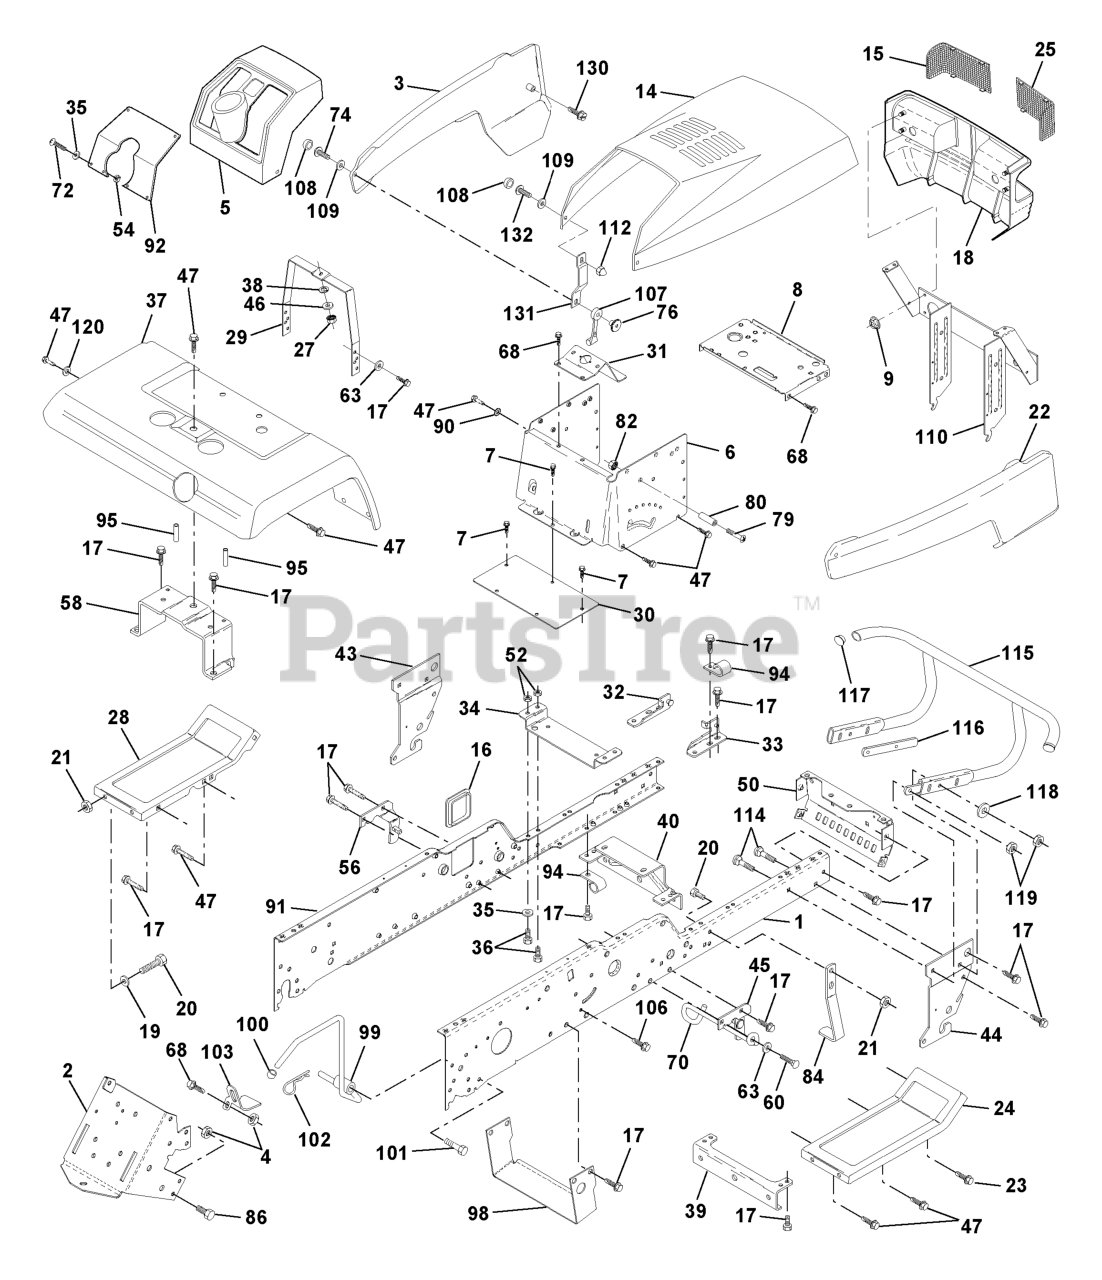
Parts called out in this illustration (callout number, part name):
1	RAIL, FRAME RH
2	DRAWBAR-GT
3	SIDE PANEL LH
4	Nut, Lock Hex 7/16 Unc
6	DASH ASS'Y LOWER
7	SCREW
8	SUPPORT, BATTERY
9	PAL NUT LT
14	HOOD ASM PNT
15	LENS LH
16	COVER ACCESS
17	SCREW
18	GRILL COMPLETE
19	WASHER
20	BOLT
22	PANEL ASM SD RH
23	SCREW GTV
24	FOOTREST RH
25	LENS RH
27	NUT
28	FOOT REST LH
29	DASH SUPT YP
30	SADDLE.HYDRO.95
31	BRACE, SUPPORT STEERING
32	FRAME PIVOT BRKT ASSY LH
33	FRAME PIVOT BRKT ASSY RH
34	ENGINE SUPPORT BRKT
35	WASHER
36	BOLT.FIN.HEX.5/16-18X3/4
37	FENDER
38	LOCKWASHER
39	FRONT AXLE BRACKET
40	AXLE SUPPORT BRKT
43	FRONT SUSPENSION BRKT LH
44	FRONT SUSPENSION BRKT RH
45	BRACKET SUSP RH
46	WASHER PM
47	SCREW LT
50	BRACKET, CHASSIS FRONT
52	NUT.71038.31-18.HEX.NYLOCK
54	NUT
56	BRACKET ASM, SUSP CHASSIS
58	FENDER BRKT
60	SCREW
63	WASHER
68	Screw, Thdrol 5/16-18 x 1/2
70	BELT GUIDE
72	Screw, Mach Trhd 5/16-18 x 3/4
74	SCREW
76	WELDNUT
79	RP SCREW
82	NUT **
84	MOWER STOP
86	BOLT
90	LOCKWASHER
91	RAIL, FRAME LH
92	DASH PLATE
95	NUT-PUSH YT
98	BRACKET CHASSIS
99	ROD ASMBLY BYPASS
100	CAP
101	SCREW LT
102	RETAINER M
103	BRACKET LOCK BYPASS
106	SCREW
107	LATCH.HOOD.
108	SNAP CAP LT
110	PIVOT ASM GRL/HD
112	NUT
114	BOLT.3/8-14X1.25
115	BUMPER ASM
116	BRACKET BUMPER
117	PLUG PLASTIC
118	WASHER
120	WASHER
130	Screw, SLTD Hex Hd. W/Pl Washer
131	BRACKET.SUPPORT.HOOD/PANEL.NLA
132	SCREW 10-24X3/8
